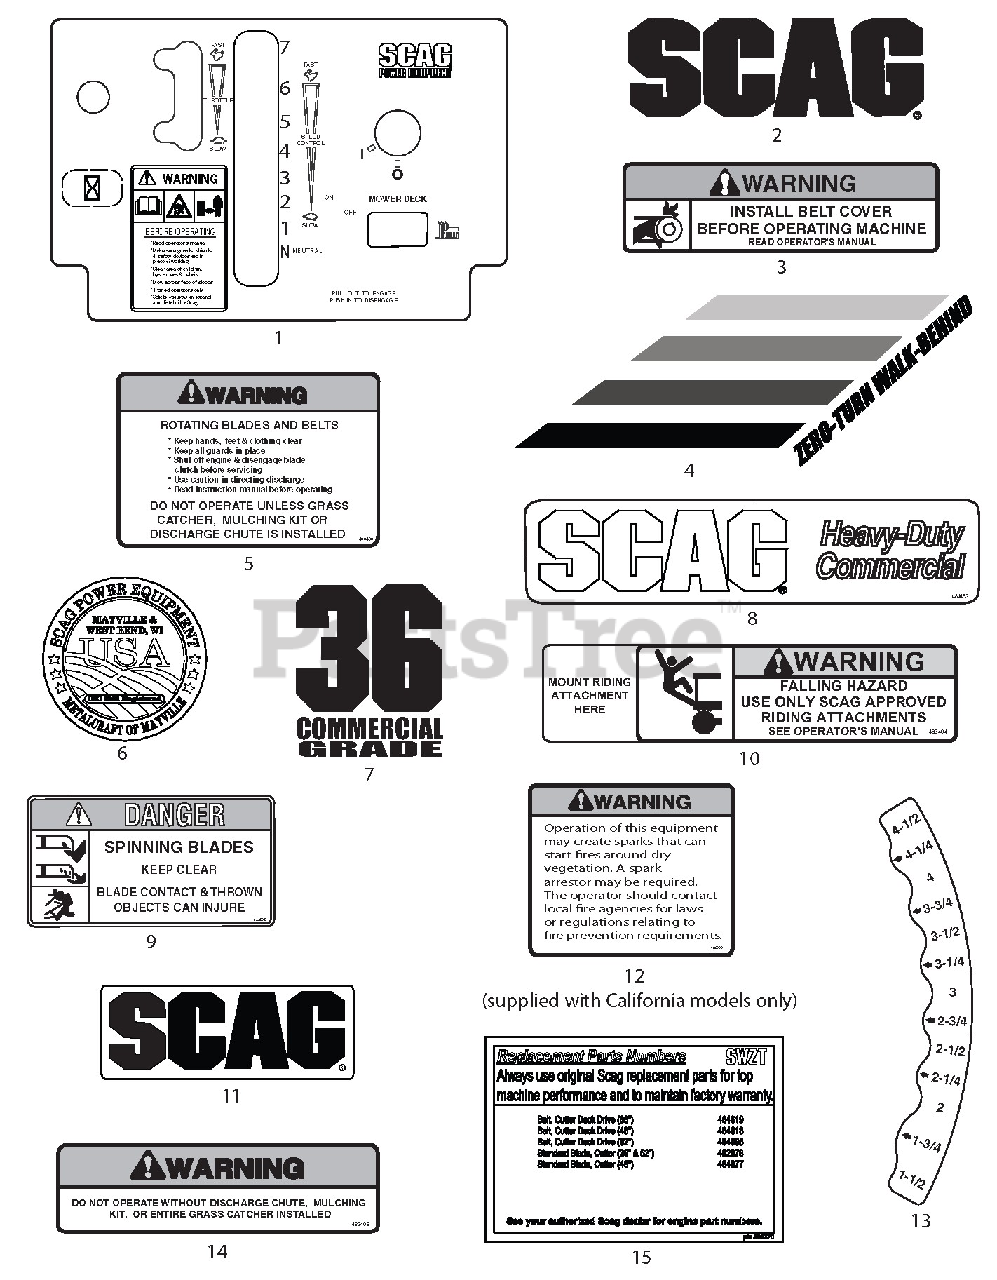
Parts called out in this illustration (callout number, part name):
1	Decal, Instrument Panel (Manual Start)
1	Decal, Instrument Panel (Electric Start Only)
2	Decal, Scag Logo
3	Decal, Belt Cover
4	Decal, Handle - LH
4	Decal, Handle - RH
5	Decal, Warning-Rotating Blades
6	Decal, Metalcraft - USA
7	Decal, 36 Commercial
7	Decal, 48 Commercial
7	Decal, 52 Commercial
8	Decal, Scag Heavy Duty
9	Decal, Spinning Blades
10	Decal, Sulky Attachment
11	Decal, Scag Logo
12	Decal, Warning Spark Arrestor
13	Decal, Height of Cut
14	Decal, Warning
15	Decal, SWZT Replacement Parts
